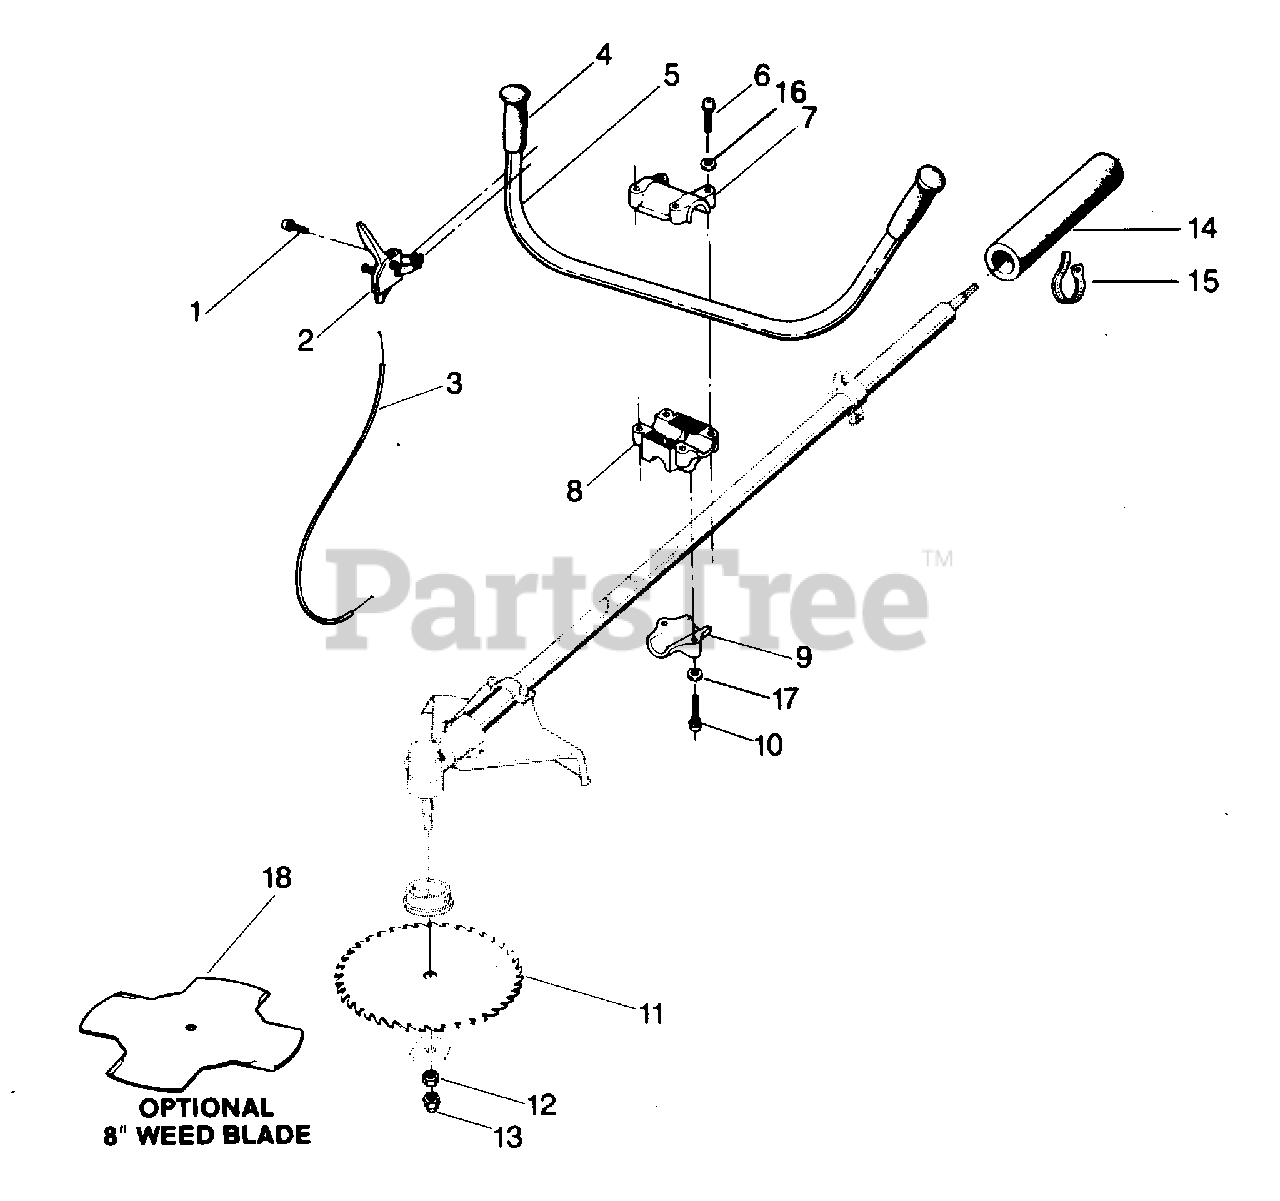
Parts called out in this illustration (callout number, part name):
1	Screw - Phil. Hd. - 5 x 25mm.- Throttle Control
2	Ass'y. - Throttle Control
3	Cable - Throttle
4	Grip - Handlebar
5	Handlebar - "U"
6	Bolt - Clamp - Top
7	Cover - Top - Clamp
8	Clamp - Handlebar
9	Cover - Bottom - Clamp
10	Bolt - Clamp - Bottom
11	Brush Blade - 10"
12	Lock Nut - Blade
13	Cap - Nut - Blade
14	Drive Shaft Pad
15	Tie Strap
16	Lockwasher - 10
17	Lockwasher - 10
18	Weed Blade - 8 inch - Optional
